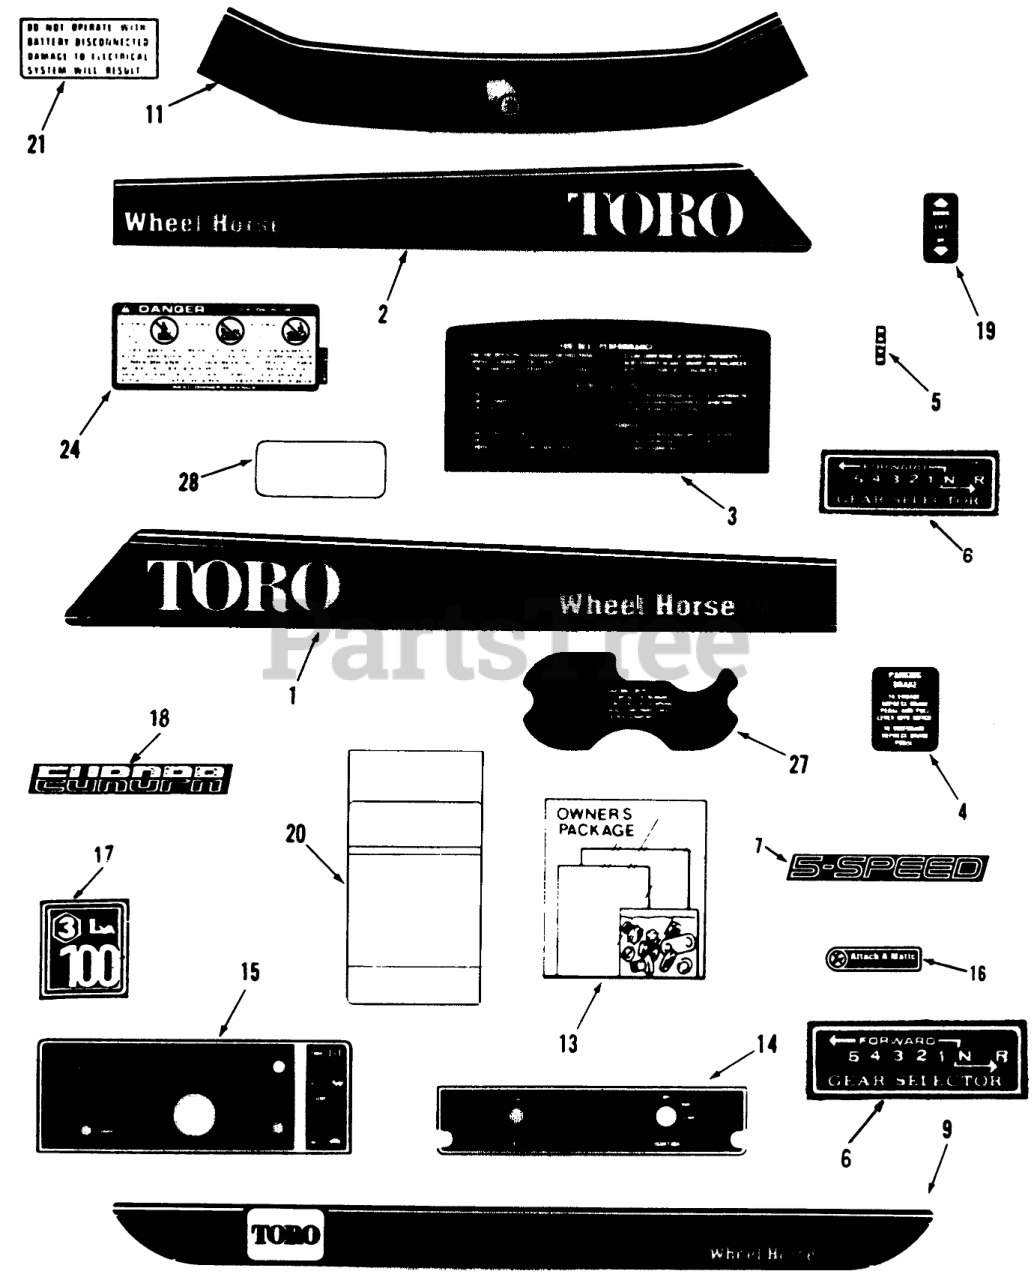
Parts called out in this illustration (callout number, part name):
1	DECAL-HOOD 227-5 R H
2	DECAL-HOOD 227-5 L H
3	Decal-Rear Hood
4	DECAL-PARKING-BRAKE
5	DECAL PTO CLUTCH
6	DECAL SHIFT
7	DECAL-MODEL 5-SPEED
9	DECAL-FENDER
11	DECAL-FRONT HOOD
13	New Tractor Loose Parts Package 227-5
14	DECAL-BACK PLATE
15	DECAL-LOWER DASH
16	Decal-Attac-O-Matic
17	DECAL-EUROPE
18	DECAL-EUROPA
19	DECAL-LIFT
20	MAINTENANCE-DECAL
21	DECAL ELECT SYSTEM
24	DECAL-DANGER
27	DECAL-SEAT LIFTER
28	DECAL-OVERLAY
